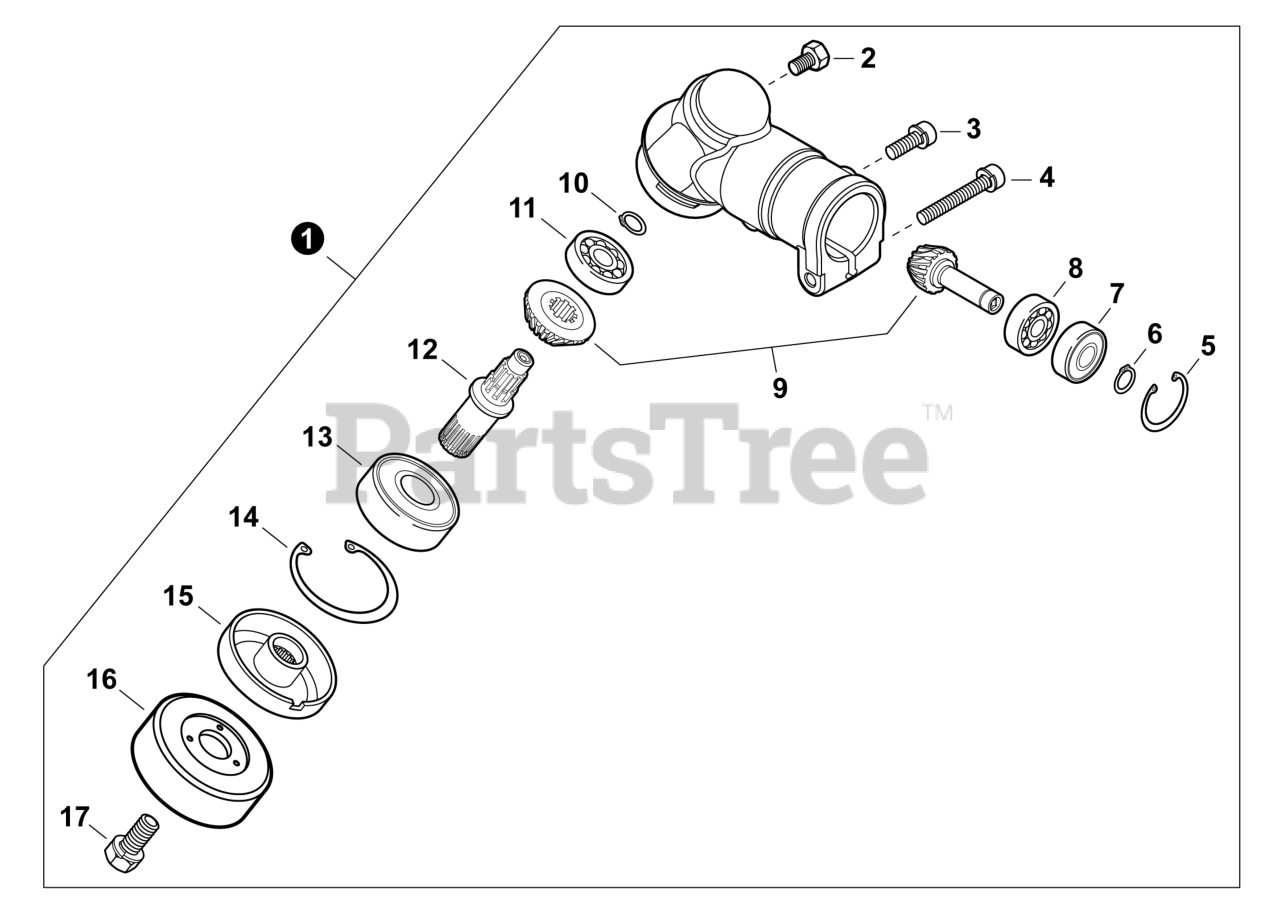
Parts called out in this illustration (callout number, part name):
1	GEAR CASE ASSY
2	BOLT M8×8
3	SCREW 5×12
4	BOLT M5×35
5	RING, SNAP 24
6	RING, SNAP Ø9
7	BEARING, BALL 609
8	BEARING, BALL 609
9	GEAR SET
10	RING, SNAP Ø6
11	BEARING, BALL 626 DDU
12	SHAFT, GEAR
13	BEARING, BALL 6000DDU
14	RING, SNAP 26
15	PLATE, ADAPTOR - UPPER
16	GUARD, BOLT
17	BOLT M7×1.0
